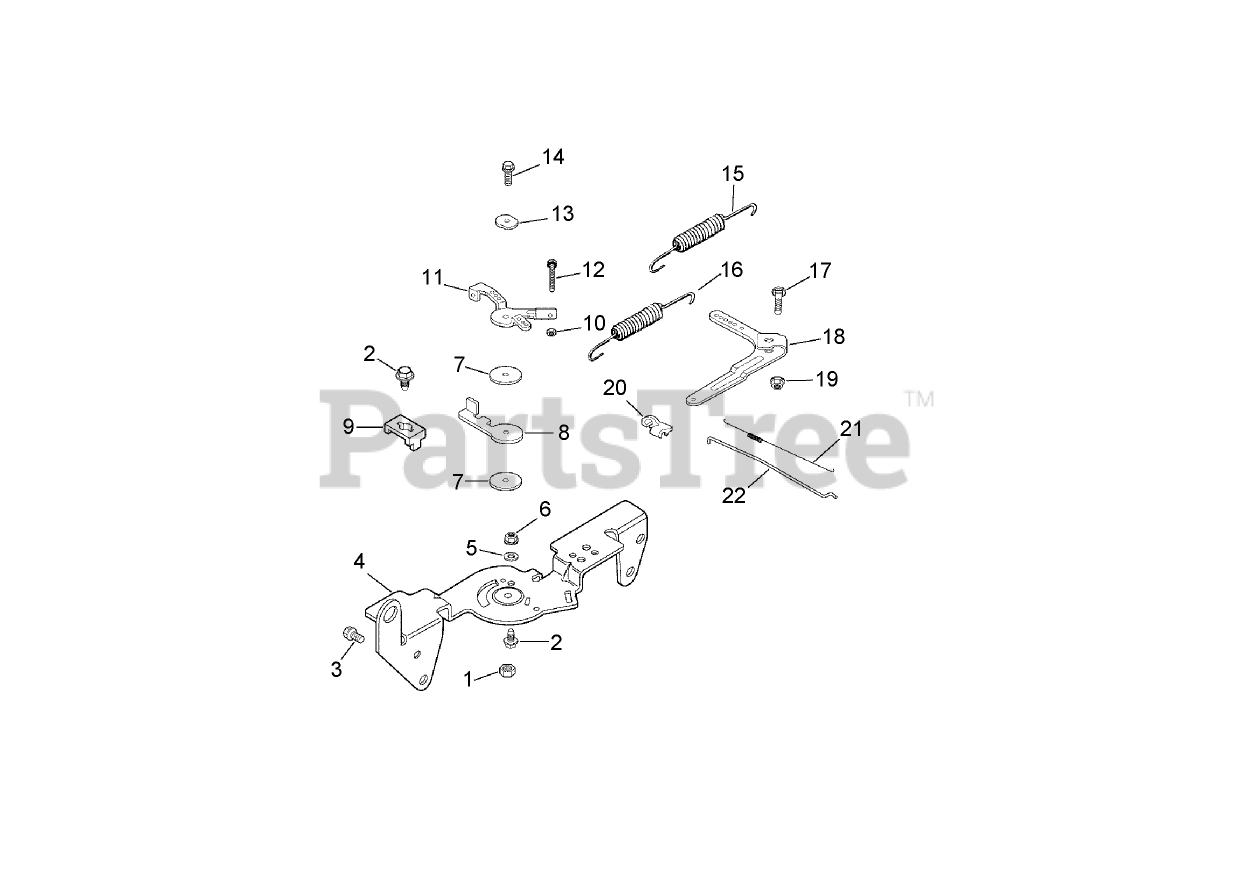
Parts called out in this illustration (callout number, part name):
1	NUT-LOCK (M5X.8)
2	SCREW-FLANGE, THREAD FORMING (M5X0.8X16)
3	SCREW-FLANGE, THREAD FORMING (M6X1.0X16)
4	Bracket-Control
5	Washer-Lock (.25)
6	Nut-HF (M5x0.8)
7	WASHER-FLAT (5.5MM)
8	Lever-Actuator, Throttle
9	CLAMP-CABLE
10	NUT (M4X0.7)
11	Lever-Control, Throttle
12	Screw (M4x0.7x30)
13	WASHER-SPRING (1/4)
14	SCREW-FLANGE, THREAD FORMING (M5X.8X20)
15	Spring-Limiter, Throttle
16	Spring-Governor
17	BOLT-SQ NECK, RD HD (M6X1.0X25)
18	Lever-Governor
19	NUT-FLANGE (M6X1.0)
20	BUSHING-RETAINING, LINKAGE
21	Spring-Linkage
22	Linkage-Throttle
